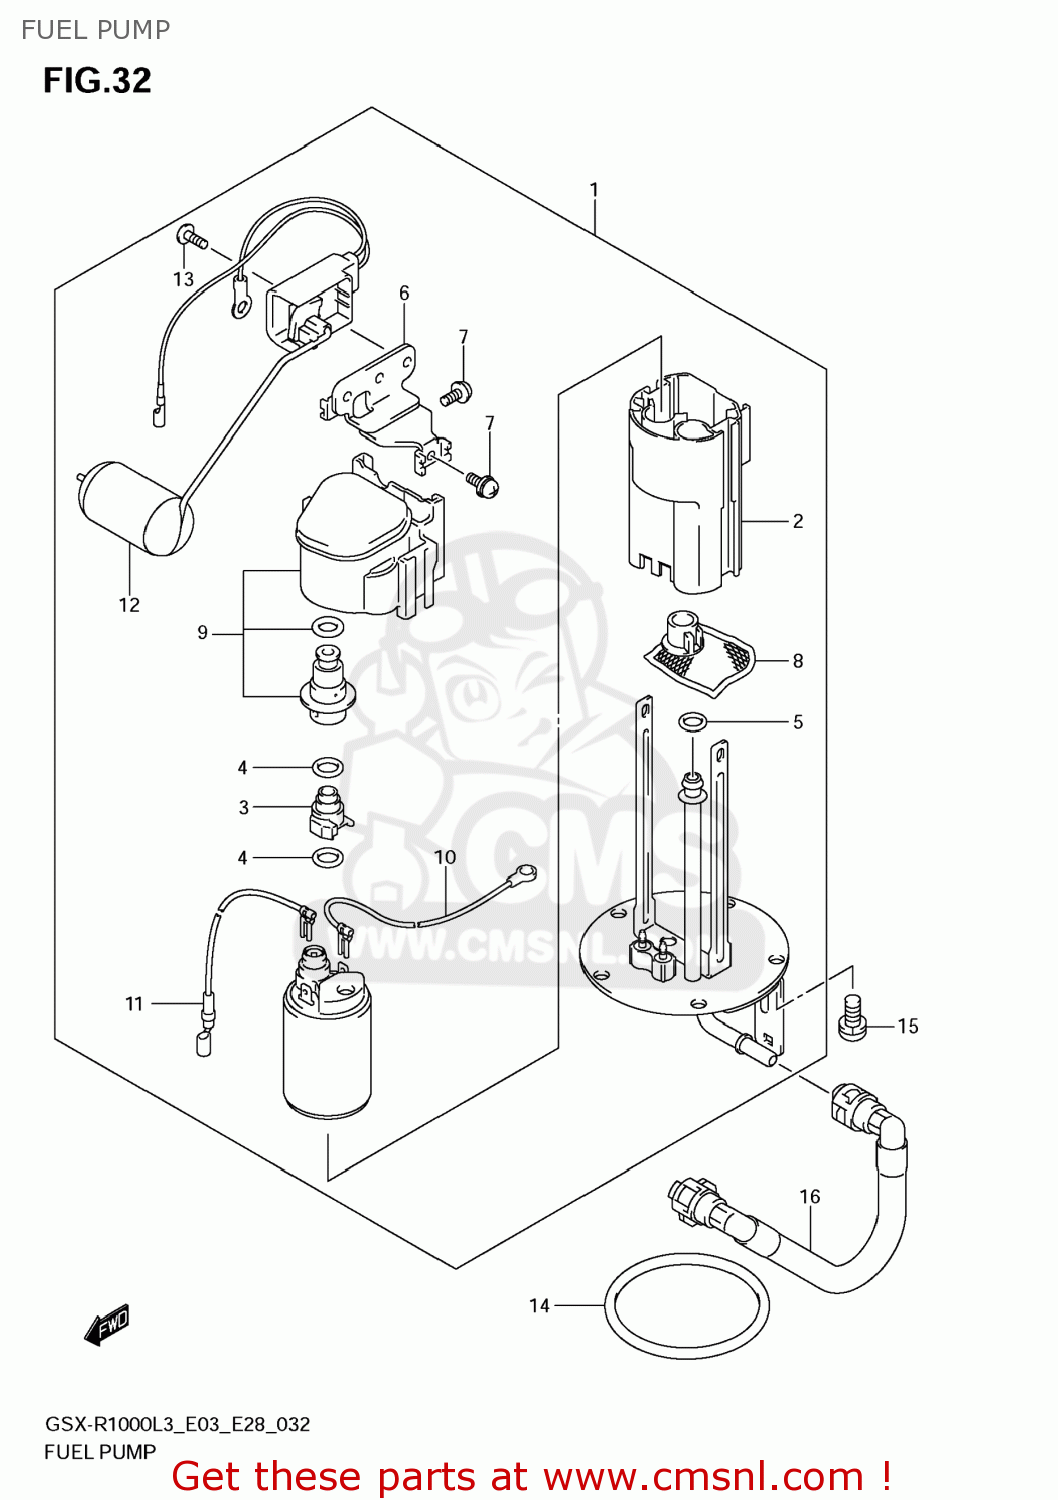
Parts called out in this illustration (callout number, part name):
1	PUMP ASSY,FUEL
2	CUP
3	JOINT
4	O RING
5	O RING
6	BRACKET
7	SCREW
8	STRAINER
9	REGULATOR,FUEL
10	WIRE,EARTH
11	WIRE,LEAD
12	GAUGE ASSY,FUEL LEVEL SENDER
13	SCREW
14	O RING,FUEL PUMP
15	BOLT
16	HOSE,FUEL
